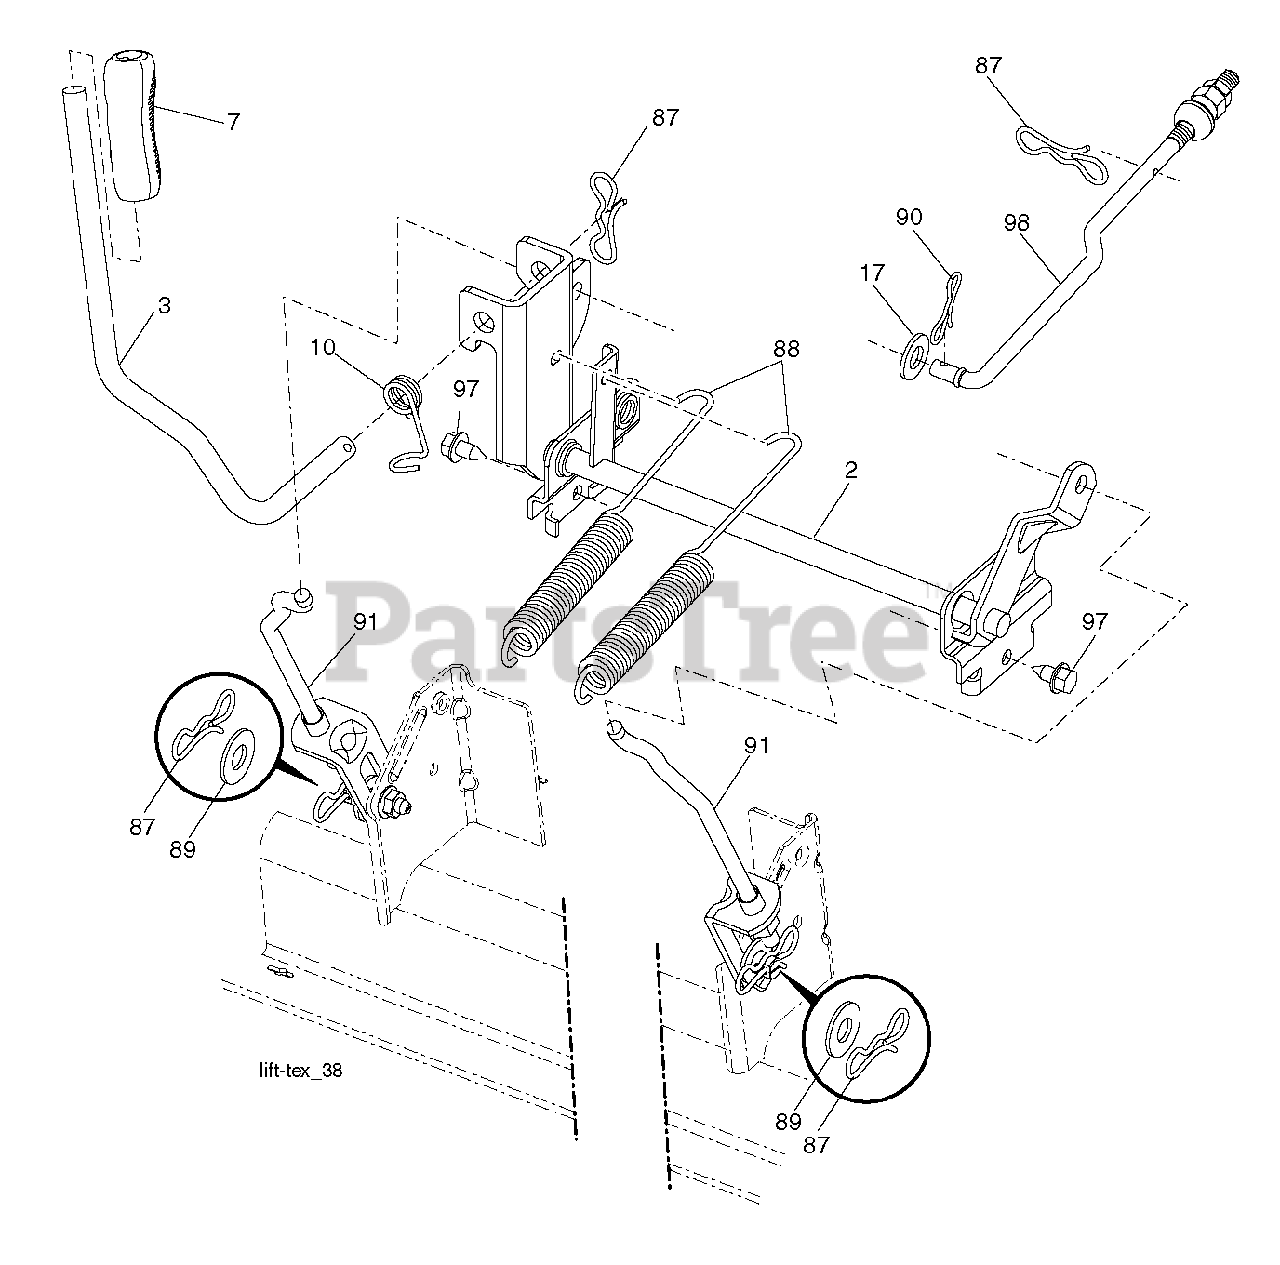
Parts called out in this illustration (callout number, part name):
2	SHAFT.ASM.CROSS.LIFT
3	LEVER.LIFT.HANDLE.LT
7	GRIP.HANDLE.LIFT.PVC.BLACK
10	SPRING.TORSION.LIFT.HANDLE
17	WASHER
87	PIN.COTTER.7/16.BOW TI.
88	SPRING.LIFT.ASSIST
89	WASHER.CLEAR.ZINC
90	PIN.COTTER.5/16.BOW TI
91	LINK.ASM.LIFT.54"TG
97	SCREW, 3/8-16X3/4
98	LINK.ASM.SUSP.FRONT.MWR.10.5
